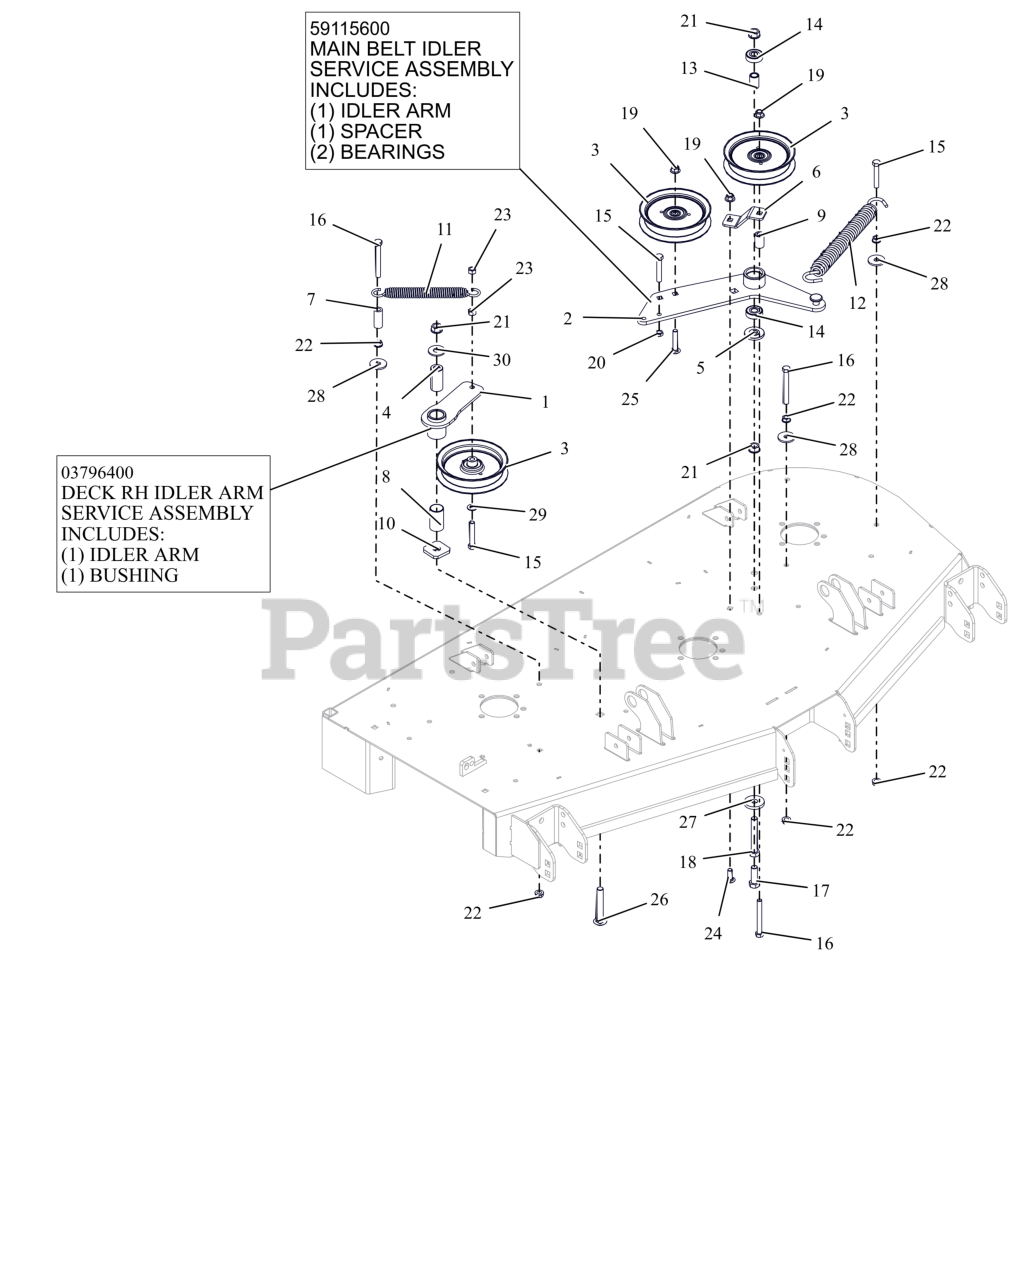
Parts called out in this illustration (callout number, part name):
1	WMT, IDLER ARM - BLACK
1	ASM, IDLER ARM (DECK)
2	WLDMT, DECK PTO IDLR ARM
2	ASSEMBLY, MAIN BELT IDLER
3	IDLER, FLAT 5.00"
4	BSHG, SPCR .502X.997X2.03 PM
5	SPACER, IDLER ARM
6	PTO FIXED IDLER MTG BRKT -RED
7	HOSE, .38 X 1.65
8	BSHG, 1.00X1.125X1.937
9	BUSHING, SLV .380X.750X1.190
10	WSHR-FLT .640X1.75X.250
11	SPRING, EXTENSION
12	SPRING, EXTENSION
13	SPACER .510 X .75 X 1.1485
14	BRG-BALL .500X1.38X.437
15	BLT,HEX .38-16X2.25 G5 ZCC
16	BLT, HEX .38-16X3.25 G5 ZCC
17	BLT,HEX .50-13X1.50 G5 ZCC
18	BLT,HEX .50-13X3.25 G5 ZCC
19	NUT,NYL-FLG .38-16 GF ZCC
20	NUT-JAM .375-16 G2 ZCC
21	NUT-LK-CTR-FLG .500-13 GG ZCC
22	NUT, SPNLK-FLG .38-16 G5 ZCC
23	NUT-LK-CTR .38-16 ZC120
24	BLT,RHSSN .38-16X1.00 G5 ZCC
25	BLT,RHSSN.375-16X2.00 G5 ZCC
26	BTL,RHSSN .500-13 X 3.25 G5 ZCC
27	WSHR-FL-STL 0.557X1.625X0.25 ZCC
28	WSHR,FLT .406X1.375X.135 ZCC
29	WSHR,FLT .406X.812X.065 ZCC
30	WSHR,FLT .563X1.375X.109 ZCC
